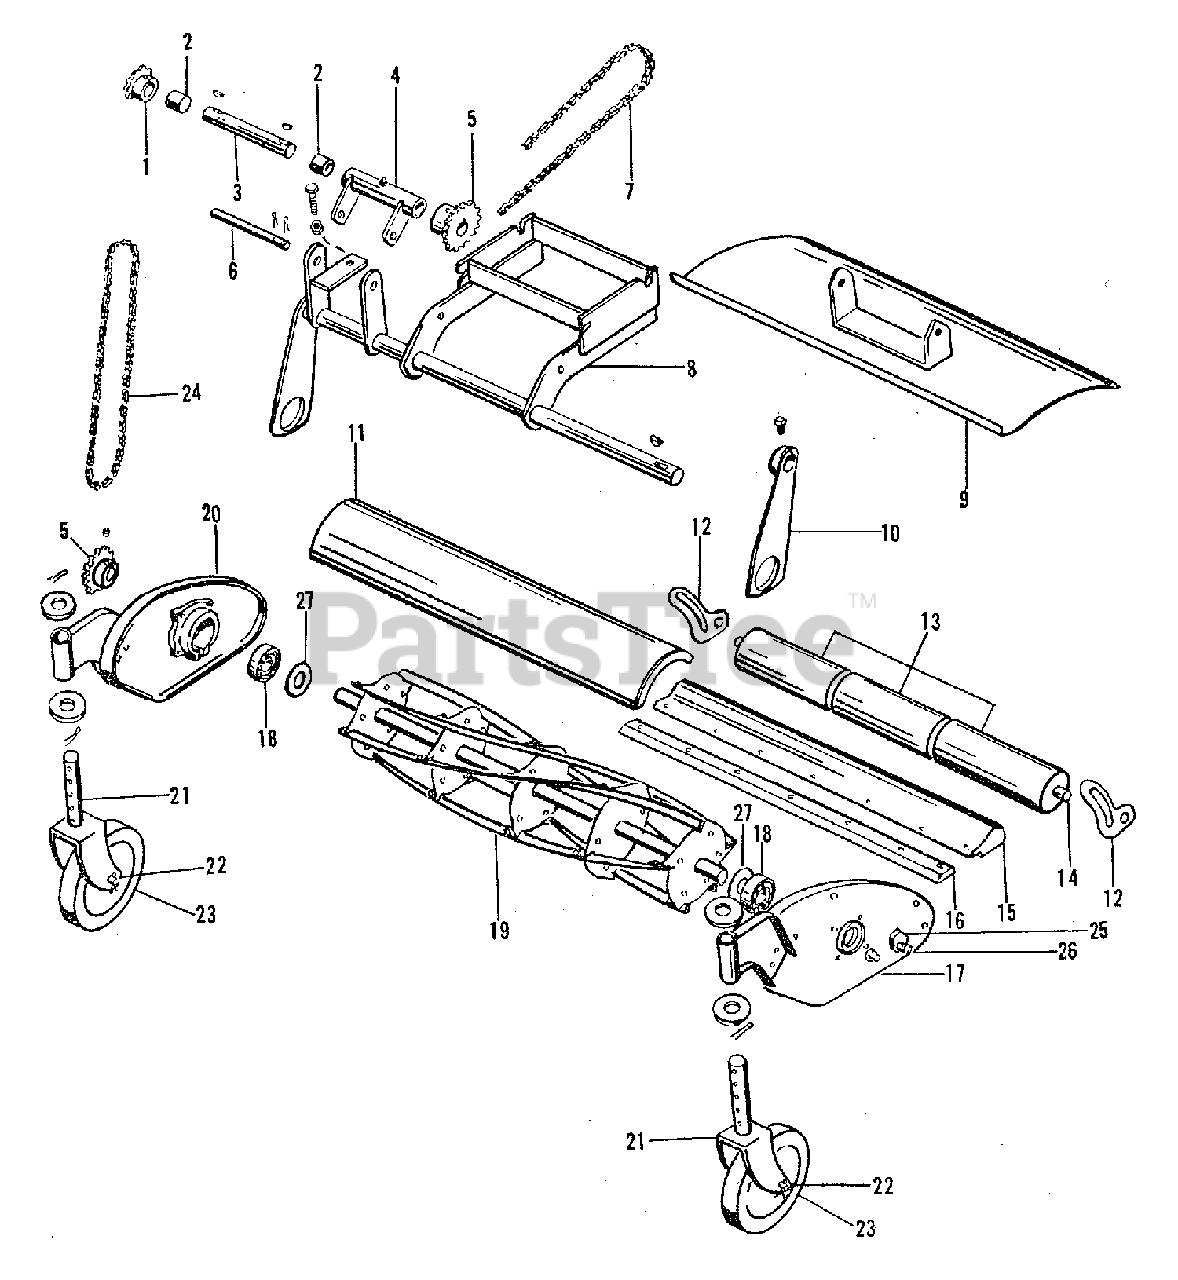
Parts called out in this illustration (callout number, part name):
2	IDLER SHAFT BEARING
3	SPROCKET SHAFT
4	SPROCKET BEARING HOUSING ASSEMBLY
6	SPROCCKET ARM SHAFT
7	DRIVE CHAIN, 29" Long
8	PUSH ARM ASSEMBLY
9	GRASS FENDER ASSEMBLY
10	PUSH BAR ASSEMBLY, L.H.
11	BAR, Brush
12	BRACKET, Roller
14	SHAFT, Roller
15	BAR, Cutter
16	CUTTER BLADE BAR, W/Rivetes
17	SIDE FRAME ASSEMBLY, L.H.
18	BEARING, Ball
19	REEL ASSEMBLY, W/Bearings
20	SIDE FRAME ASSEMBLY, R.H.
21	CASTER YOKE ASSEMBLY
22	AXLE, Caster
23	CASTER WHEEL w/Bearings
24	REEL CHAIN, 24" Long
25	ADJUSTING CAM
26	CAPSCREW, Hex Head, 3/8"-24 x 7/8
27	REEL BEARING WASHER
